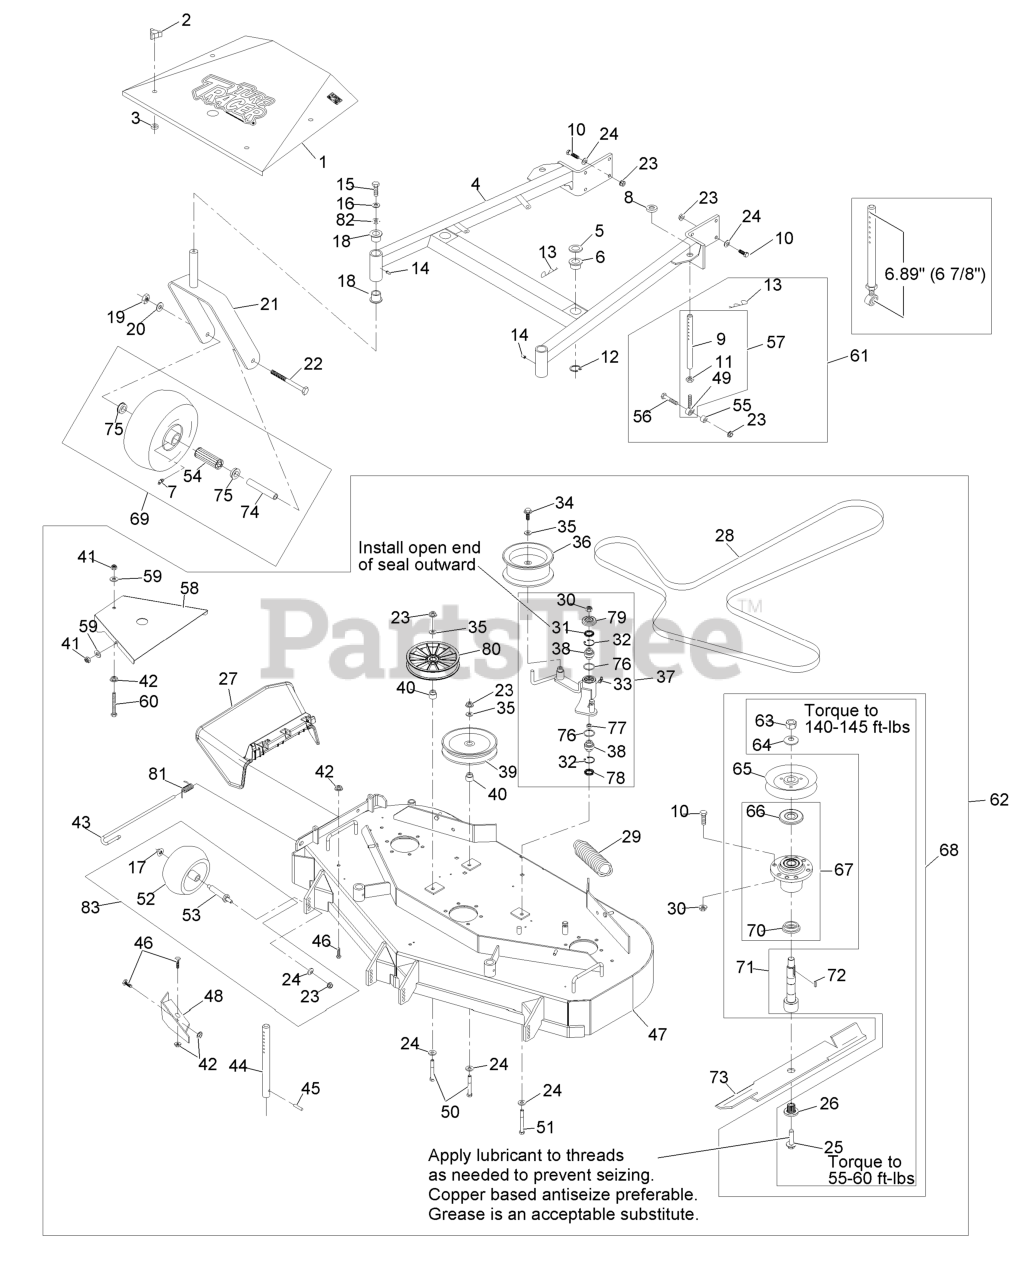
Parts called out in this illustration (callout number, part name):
1	ASM,SHIELD W/DECALS 48 TT
2	KNOB-3 PRONG
4	DECK SUPPORT W/BSHGS 48"
5	SPACER-DECK SUPPORT
6	BUSHING-DECK
7	FITTING-GREASE
9	LINK,SUPPORT
10	SCREW-HH
11	NUT-HJ
12	RING-RETAINING
13	PIN,HAIR COTTER
14	FITTING-GREASE
15	SCREW-HH
16	WASHER-LOCK
17	Nut-Nyloc 3/8-16 Flg
18	BEARING-FLANGED
19	NUT-HH
20	WASHER-LOCK
22	SCREW-HH
23	NUT-HHF, WHIZ
24	WASHER-BELLEVILLE
25	SCREW,SEMS 1/2-20 X 2.19
26	BUSHING,SPLINED
27	CHUTE DEFLECTOR XRK M056
28	BELT - V, B
30	NUT-LOCK, NI
31	SEAL-LIP, SINGLE
32	RING-SNAP
33	FITTING-GREASE, 90 DEG
34	SCREW-HHF
35	WASHER-FLAT
37	KIT, DECK IDLER TTHP48&52
38	BEARING-SPHERICAL
39	PULLEY-IDLER
40	BUSHING-IDLER
41	NUT-LOCK, NI
43	PIN-CHUTE
44	ROD,DECK SUPPORT
46	SCREW-HH
47	ASM,DECK W/DECALS TTHP/MH
48	BAFFLE,DOGLEG
49	BALLJOINT
50	SCREW-HH
51	SCREW-HH
52	ROLLER-SCALP, ANTI
54	BEARING
56	SCREW-HH
58	SHIELD,BELT
59	WASHER-FLAT
60	BOLT,TAP HH
61	KIT,SUPPORT LINK W/PIN
62	Asm, Deck Complete
65	SHEAVE,W/HUB 5.72
66	GUARD-BEARING, TOP
67	KIT, CUTTER HOUSING
68	ASM, CUTTER HSG
69	KIT, SP CASTER WHEEL REPL
70	SPACER-GUARD, BOTTOM
71	KIT, SPLINED SPINDLE 103-
72	KEY-RECTANGLE
75	BUSHING
78	SEAL-LIP, DOUBLE
79	GUARD-TOP
80	PULLEY,IDLER 5"
81	SPRING, TORSION
